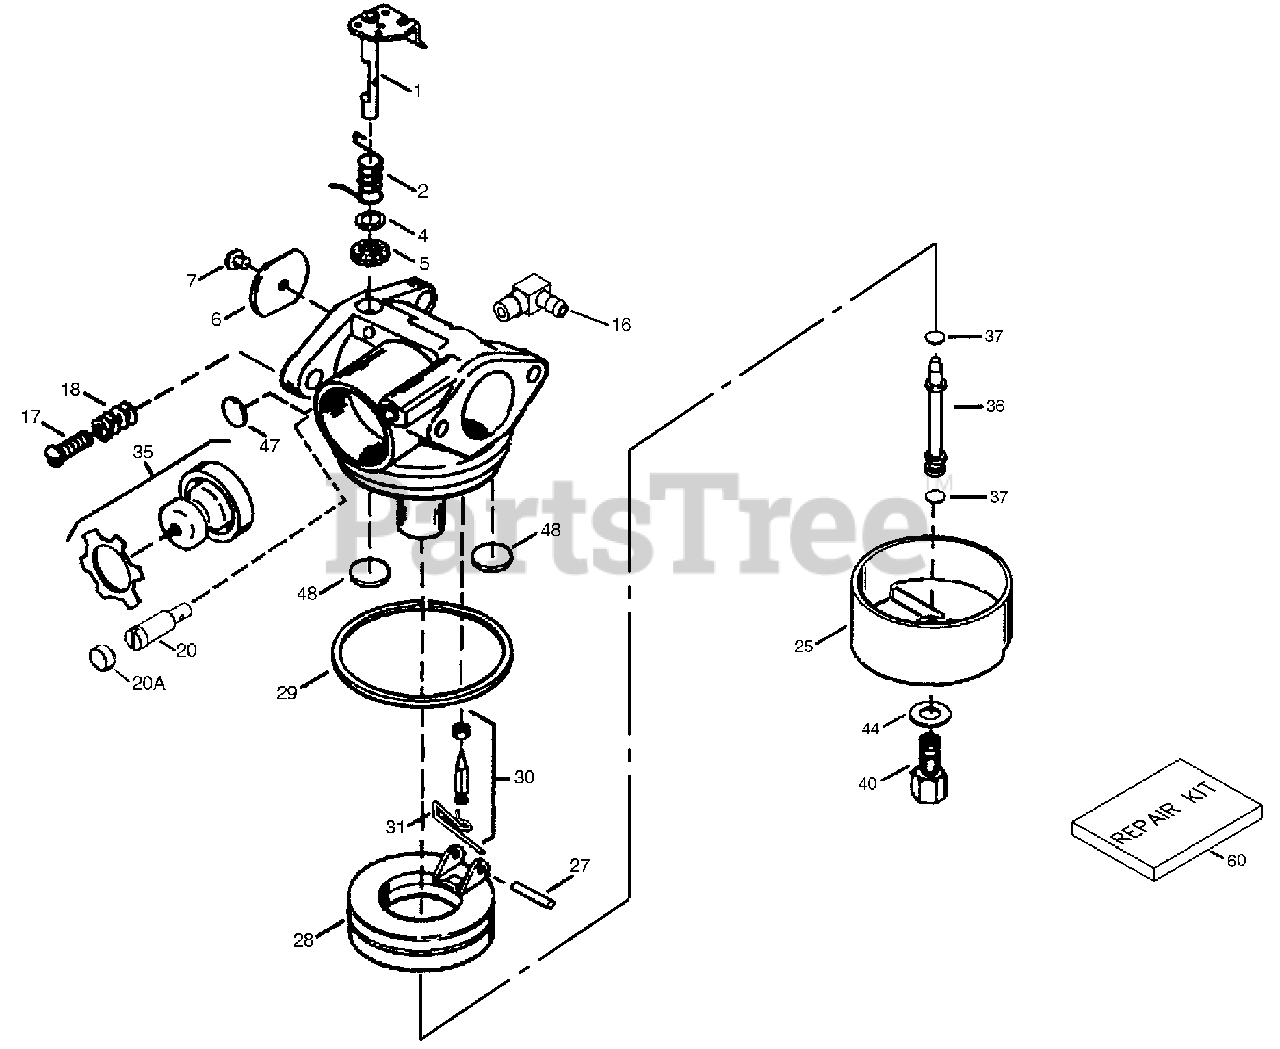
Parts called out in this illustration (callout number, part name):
1	Shaft & Lever
2	Spring-Return
4	Washer
5	Dust Seal
6	Shutter-Throttle
7	Screw
16	Fitting-Fuel
17	Screw-Idle
18	Spring
20	Idle Restrictor Screw
20A	Idle Restrictor Screw
25	Bowl, Flat
27	Float Shaft
28	Float
29	Gasket
30	Inlet Needle, Seat,& Clip (Incl. 31)
31	Clip
35	Primer Bulb/RetainerRing
36	Nozzle-Main
37	O-Ring
40	High Speed Bowl Nut
44	Washer-Bowl
47	Plug-Welch
48	Plug
60	Repair Kit
